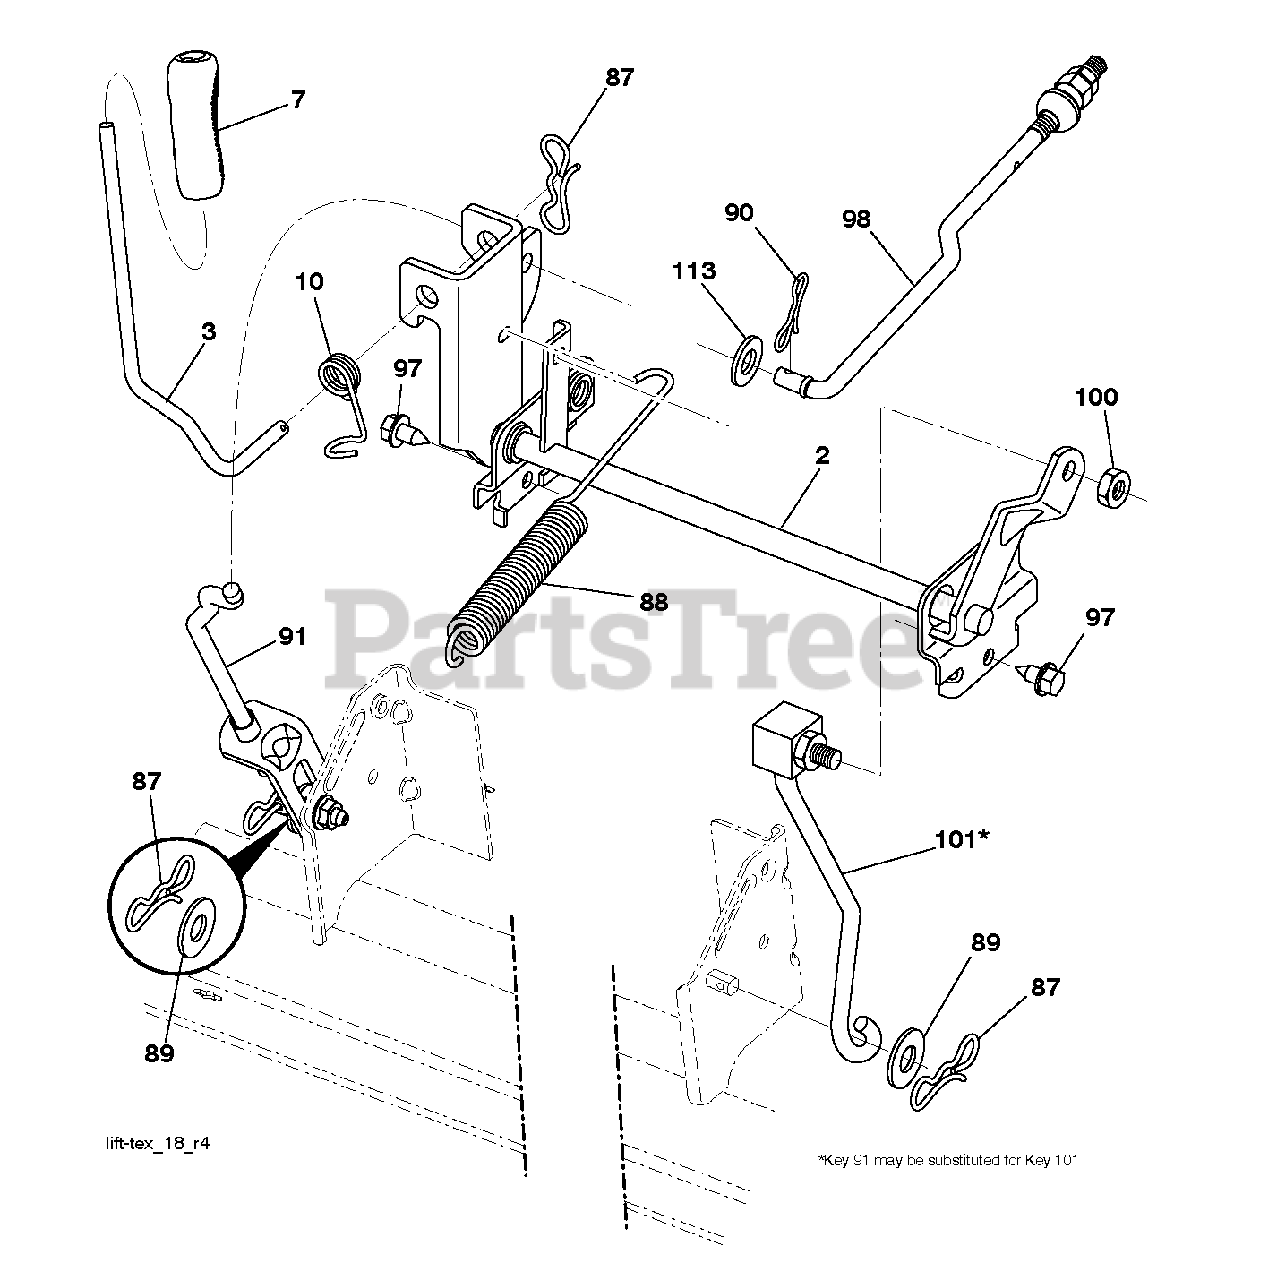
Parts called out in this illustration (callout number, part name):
2	SHAFT.ASM.CROSS.LIFT
3	LEVER.LIFT.HANDLE.LT
7	GRIP.HANDLE.LIFT.PVC.BLACK
10	SPRING.TORSION.LIFT.HANDLE
87	PIN.COTTER.7/16.BOW TI
88	SPRING.LIFT.ASSIST
89	WASHER.CLEAR.ZINC
90	PIN.COTTER.5/16.BOW TI
91	LINK.ASM.LIFT.REAR
97	SCREW, 3/8-16X3/4
98	LINK.ASM.SUSP.FRONT.MWR.10.5
100	LOCKNUT
101	LINK.ASM.LIFT.FIXE.38/42/46"
